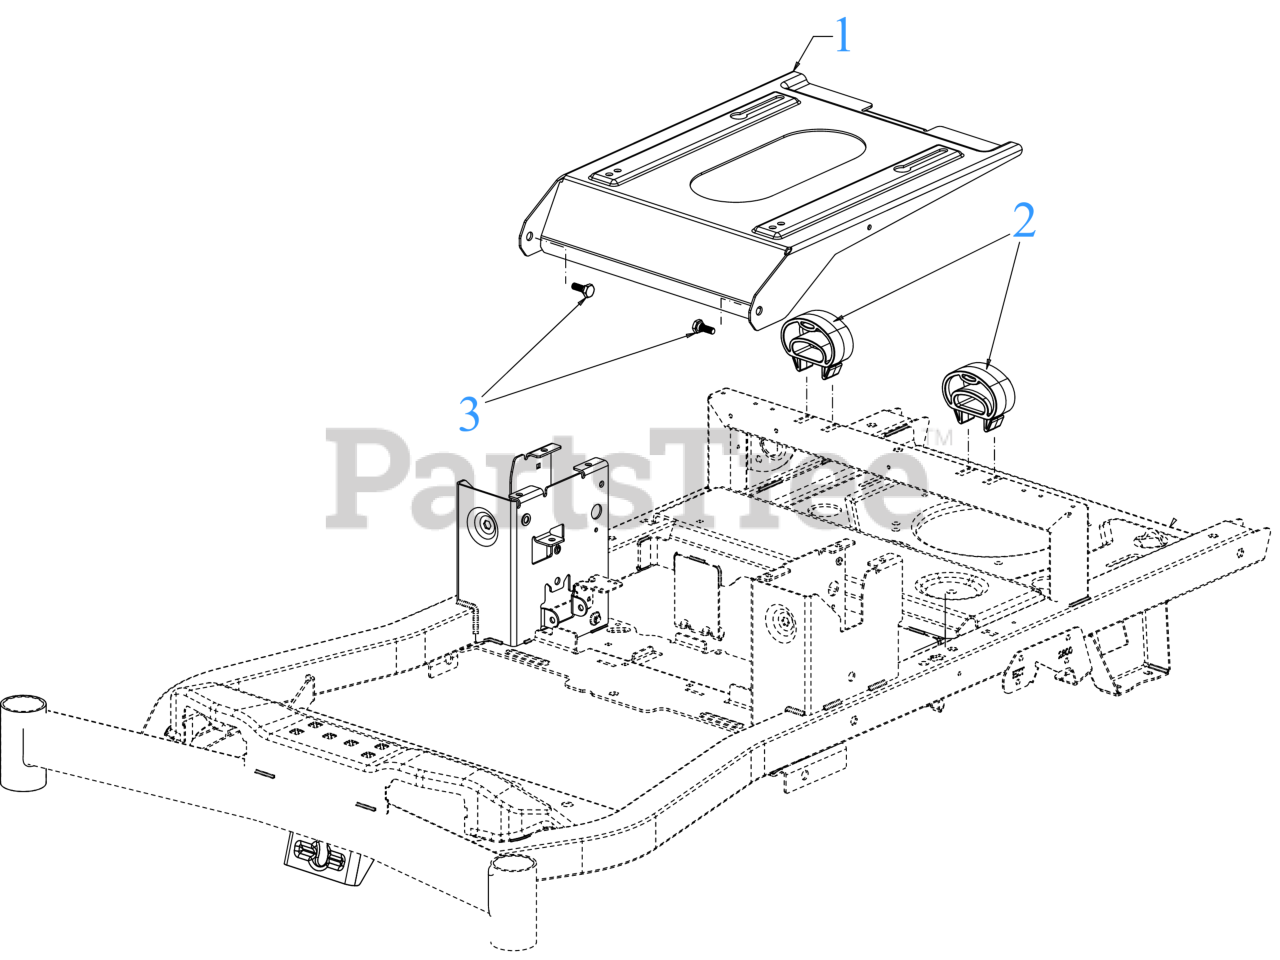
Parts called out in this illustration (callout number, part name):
1	SEAT BASE PLATE
2	POLYMER SEAT SPRING
3	SHOULDER SCREW .44DIAx.18 5/16-18
